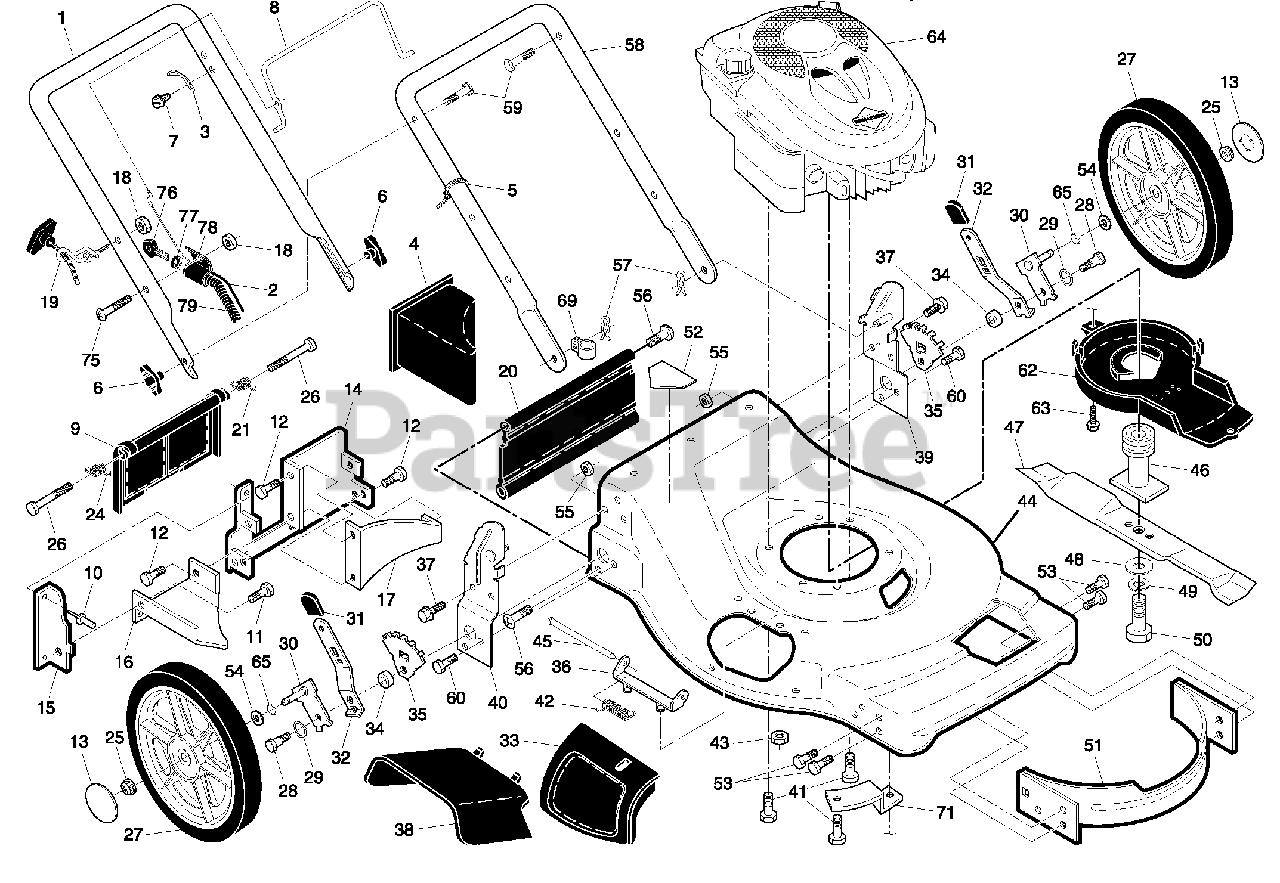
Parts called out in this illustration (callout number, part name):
1	Upper Handle
2	Cable, Operator Presence
3	Bracket, Upstop
4	Mulcher Plug
5	Wire Tie
6	Handle Knob
7	Screw
8	Control Bar
9	Rear Door Assembly
10	Pop Rivet
11	Screw, Self-Tapping #10-24 x 5/8
12	Screw, Hex Hex Head, Sems 1/4-20 x 1/2
13	Hubcap
14	Back Plate
15	Side Baffle
16	Discharge Baffle
17	Rear Baffle
18	Keps Locknut 1/4-20
19	Rope Guide
20	Rear Skirt
21	Spring, Rear Door, LH
24	Spring, Rear Door, RH
25	Nut, Hex, Flanged
26	Bolt, Rear Door
27	Wheel & Tire Assembly, Rear
28	Bolt, Shoulder 3/8-16 x 1
29	Washer, Curved, Cylindrical
30	Axle Arm Assembly
31	Selector Knob
32	Selector Spring
33	Mulcher Door
34	Spacer
35	Wheel Adjusting Bracket
36	Hinge Bracket Assembly
37	Screw, Sems, Thread Cutting 5/16-18 x 3/4
38	Discharge Deflector
39	Handle Bracket Assembly, LH
40	Handle Bracket Assembly, RH
41	Screw, Hex Head, Threaded, Rolled 3/8-16 x 1-1/8
42	Spring, Torsion
43	Nut, Hex, Nylock
44	Kit, Mower Housing
45	Rod, Hinge
46	Blade Adapter / Pulley
47	Blade, 22"
48	Washer, Hardened
49	Washer, Helical
50	Screw, Machine, Hex Head 3/8-24 x 1-3/8 Grade 8
51	Kit, Front Baffle
52	Danger Decal
53	Screw, Serrated, TT 1/4-20
54	Washer, Flat
55	Nut, Hex 3/8-16
56	Hinge Screw 1/4-20 x 1-1/4
57	Hairpin Cotter
58	Lower Handle
59	Handle Bolt
60	Bolt, Hex Head 3/8-16 x 3/4
62	Debris Shield
63	Screw, Debris Shield
65	O-Ring
69	Clip, Cable
71	Mounting Bracket, Debris Shield
75	Screw
76	Key
77	Nut, Cap
78	Key Start Switch
79	Wiring Harness
79	Operator's Manual, English
79	Operator's Manual, French
79	Repair Parts Manual
